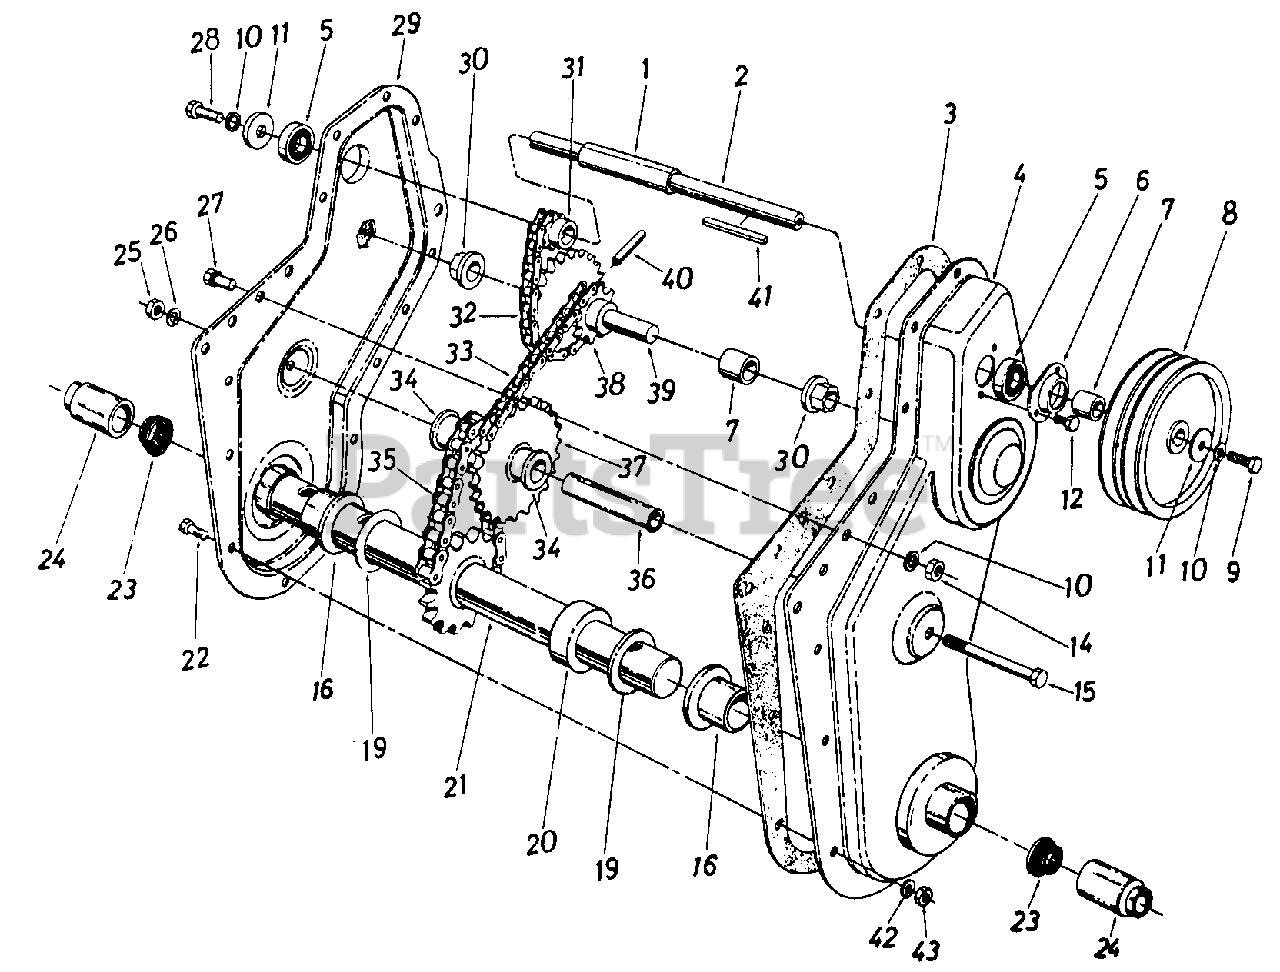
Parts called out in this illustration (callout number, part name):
2	SHAFT-JACK
3	GASKET
4	CHAIN CASE HALF-LH
5	BEARING-BALL
6	HOUSING-BRG
7	SPACER-.635 ID X .88 OD X 1.03
9	SCREW-HEX 5/16-18 X 10 SPEC
10	WASHER-LOCK-5/16
11	WASHER-FL-.312 X 1.125 X .125
12	SCREW-HEX WASH SF TAPP
14	NUT-HEX 5/16-18
15	SCREW-HEX 3/8-16 X 3.25
16	BEARING-KING PIN
19	WASHER-FL-1.03 ID X 1.62 X .03 HD
21	SHAFT-TINE
22	SCREW-HEX 1/4-28 X .62
24	CAP-DUST
25	NUT-HEX 3/8-16
26	WASHER-LOCK-3/8
27	SCREW-HEX SEMS 5/16-18 X 1.00
28	SCREW-HEX 5/16-18 X .62
29	CHAIN CASE HALF-RH
30	BEARING-HEX FLANGE
31	SPROCKET ASSY-10T
32	#41 CHAIN 1/2 PITCH X 34 LINKS E
33	#420 CHAIN 1/2 PITCH X 48 LINKS
34	BEARING-FLANGE .626 ID
35	#50 CHAIN 5/8 PITCH X 28 LINKS
36	SHAFT-SPROCKET
37	SLEEVE ASSY-SPRKT
38	SLEEVE ASSY-SPRKT
39	SHAFT-SPROCKET
40	PIN-SPRING SPIRAL 1/4X1.5 HEAVY DT
41	KEY-SQ 3/16X1.50
42	LOCK WASHER 1/4 DIA
43	NUT-HEX 1/4-28
